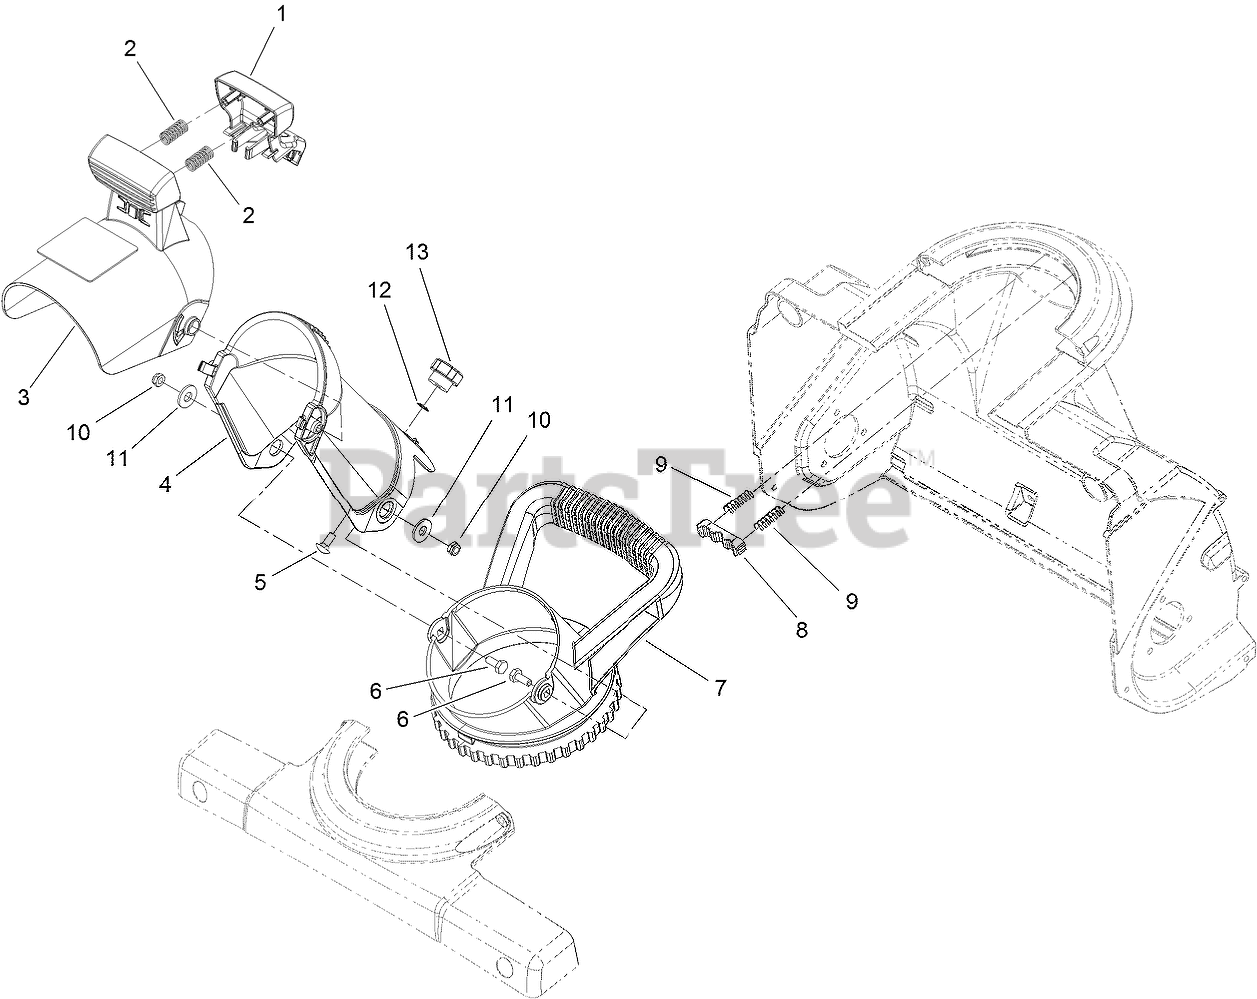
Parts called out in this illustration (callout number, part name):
1	TRIGGER-DEFLECTOR
2	SPRING-COMPRESSION
3	CHUTE DEFLECTOR ASM
4	CHUTE-DISCHARGE
5	SCREW-CARR
6	SCREW-HH
7	HANDLE-CHUTE
8	DETENT-CHUTE
9	SPRING-COMPRESSION
10	NUT-LOCK, NI
11	WASHER-FLAT
12	PUSHNUT-RETAINER, BOLT
13	KNOB-CHUTE
